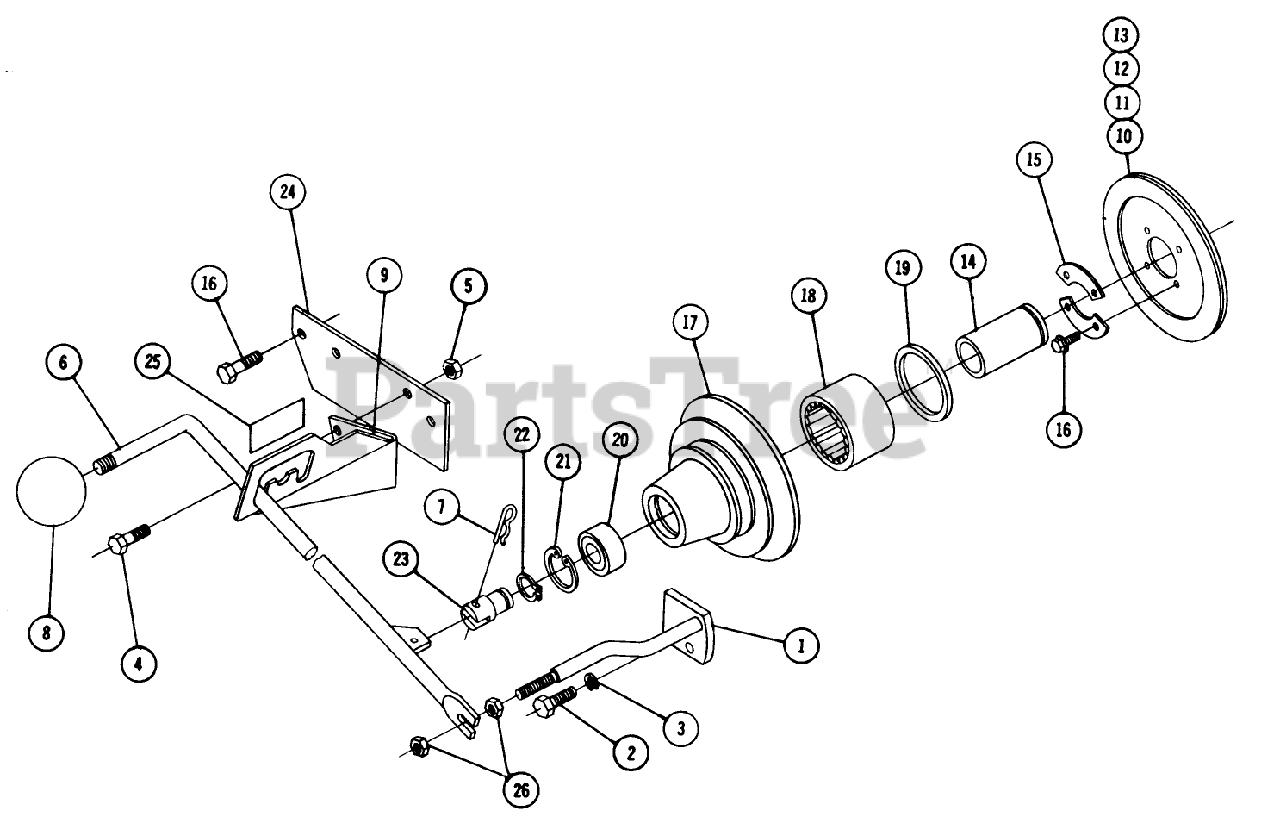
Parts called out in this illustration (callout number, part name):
1	Ass-y-Plate and Shaft
2	Bolt 3/8-16 x 3/4
3	Lockwasher
4	Bolt 5/16-18 x
5	Nut-Nylok
6	ROD ASSY
7	Hairpen
8	Knob
9	Bracket
10	L/A CLUTCHPLATE&FACI
11	Clutch Plate
12	CLUTCH FACING
13	RIVET-BRASS
14	BEARING RACE
15	RETAINER
16	Bolt, 1/4-20 Whizlock
17	Housing-Clutch
18	Seal
19	SEAL-OIL
20	Bearing
21	Snap Ring 1 3/4 Internal
22	RING-SNAP, EXTERNAL
23	SHAFT
24	Plate Adaptor
25	Decal-Clutch Adj.
26	3/8-16 E.S.
